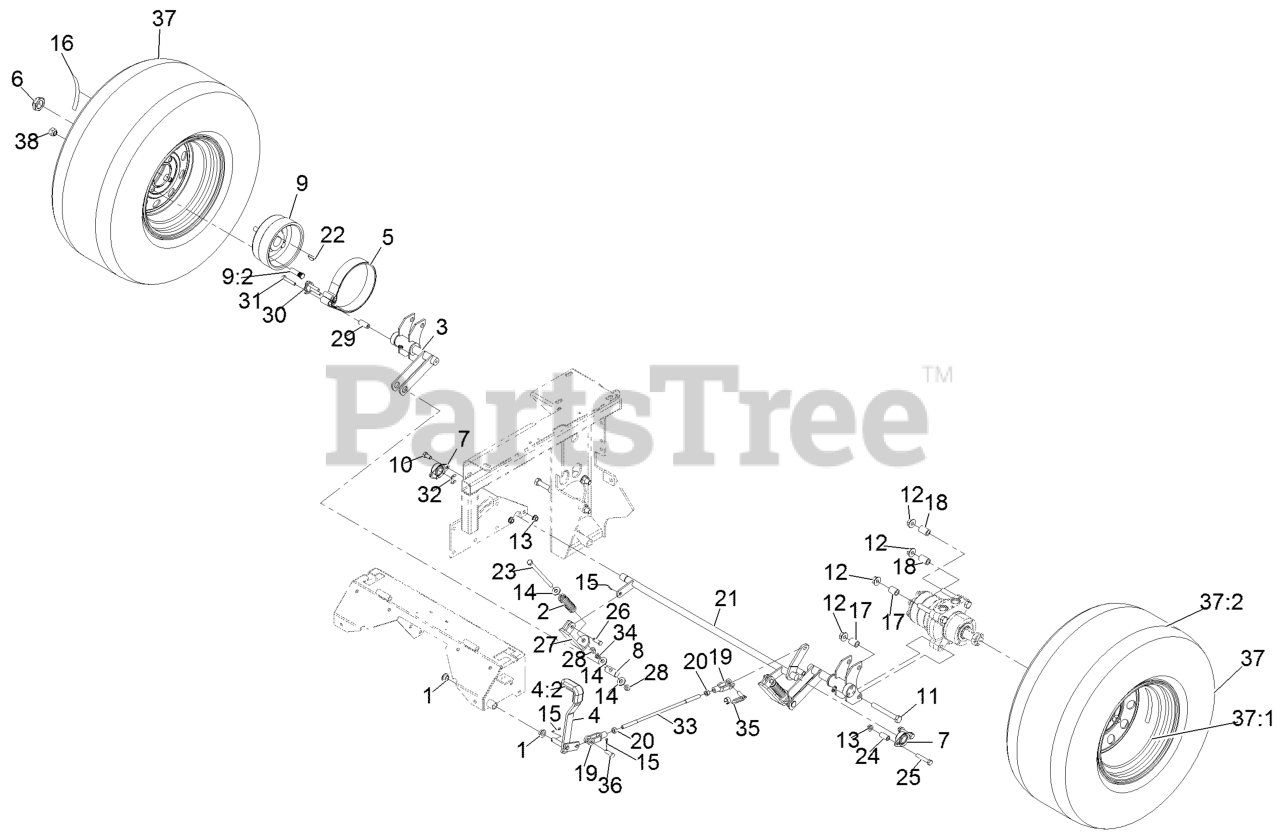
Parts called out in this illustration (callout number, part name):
1	BEARING-CONTROL
2	SPRING-COMPRESSION
3	BRAKE-WIDE
4	BRAKE LEVER AND GRIP ASM
4:2	GRIP-LEVER
5	BAND,BRAKE
6	LOCKNUT
7	BEARING-FLANGE, SIDE
8	PIN-TRUNION
9	HUB W/STUDS ASM
9:2	STUD-WHEEL
10	SCREW-HH
11	SCREW-HH
12	NUT-HHF
13	NUT-HHF, WHIZ
14	WASHER-FLAT
15	PIN-COTTER
16	DECAL-TORQUE, WHEEL HUB LUG
17	SPACER-WHEEL, SHORT
18	SPACER-WHEEL, LONG
19	YOKE-LINKAGE, BRAKE
20	NUT-HEX
21	SHAFT-BRAKE
22	KEY-WOODRUFF
23	BOLT-TAP, HH
24	SPACER-RETAINER, BRAKE
25	SCREW-HH
26	PIN-CLEVIS
27	LINKAGE-BRAKE, LOWER
28	NUT-LOCK, NI
30	RETAINER-BAND, BRAKE
31	SCREW-HH
33	ROD-BRAKE
34	NUT-JAM
35	PIN-SPRING, CLEVIS
36	PIN-CLEVIS
37	WHEEL AND TIRE ASM
38	NUT-LUG
